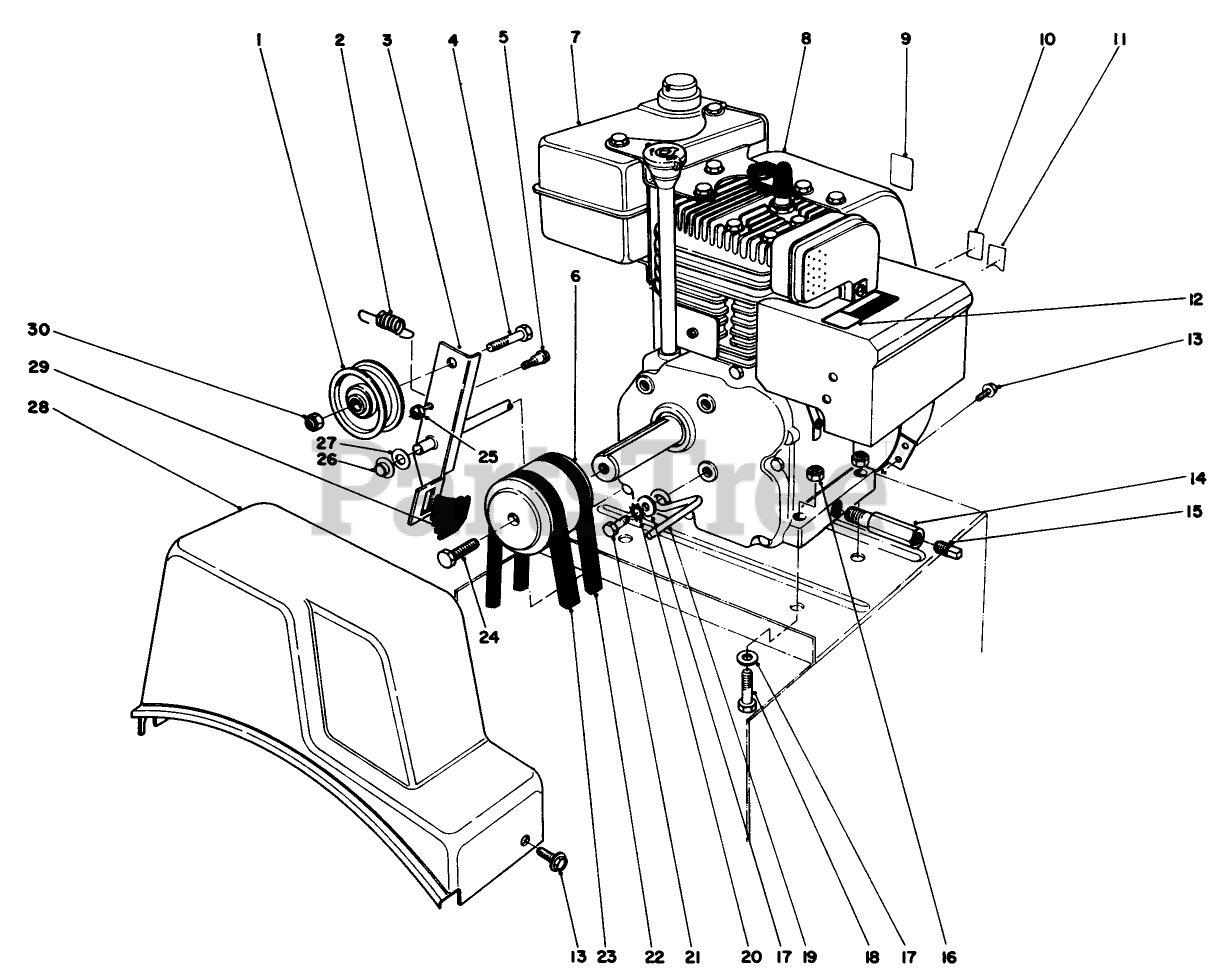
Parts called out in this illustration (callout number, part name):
1	PULLEY-IDLER
2	SPRING
3	Auger Clutch (Incl. Ref. #29)
4	SCREW-HH
5	BOLT-SHOULDER
6	PULLEY-ENGINE
7	GAS TANK 2 QT W CAP
8	Engine
9	PRIMER DECAL
10	DECAL THROTTLE
11	CHOKE DECAL
12	HOT SURFACE DECAL
13	SCREW-HWH
14	PIPE-NIPPLE
15	CAP-PIPE
16	NUT-LOCK, NI
17	WASHER-PLAIN
18	SCREW-HH
19	RETAINER-BELT
20	WASHER-LOCK
21	SCREW-HH
22	V BELT-3L, TRACTION
23	V-BELT (29.50 INCH)
24	SCREW-SPECIAL
25	NUT-LOCK, CONE
26	RETAINER-PUSH ON
27	WASHER-FLAT
28	COVER-BELT
29	Brake Pad
30	NUT-LOCK, CONE
